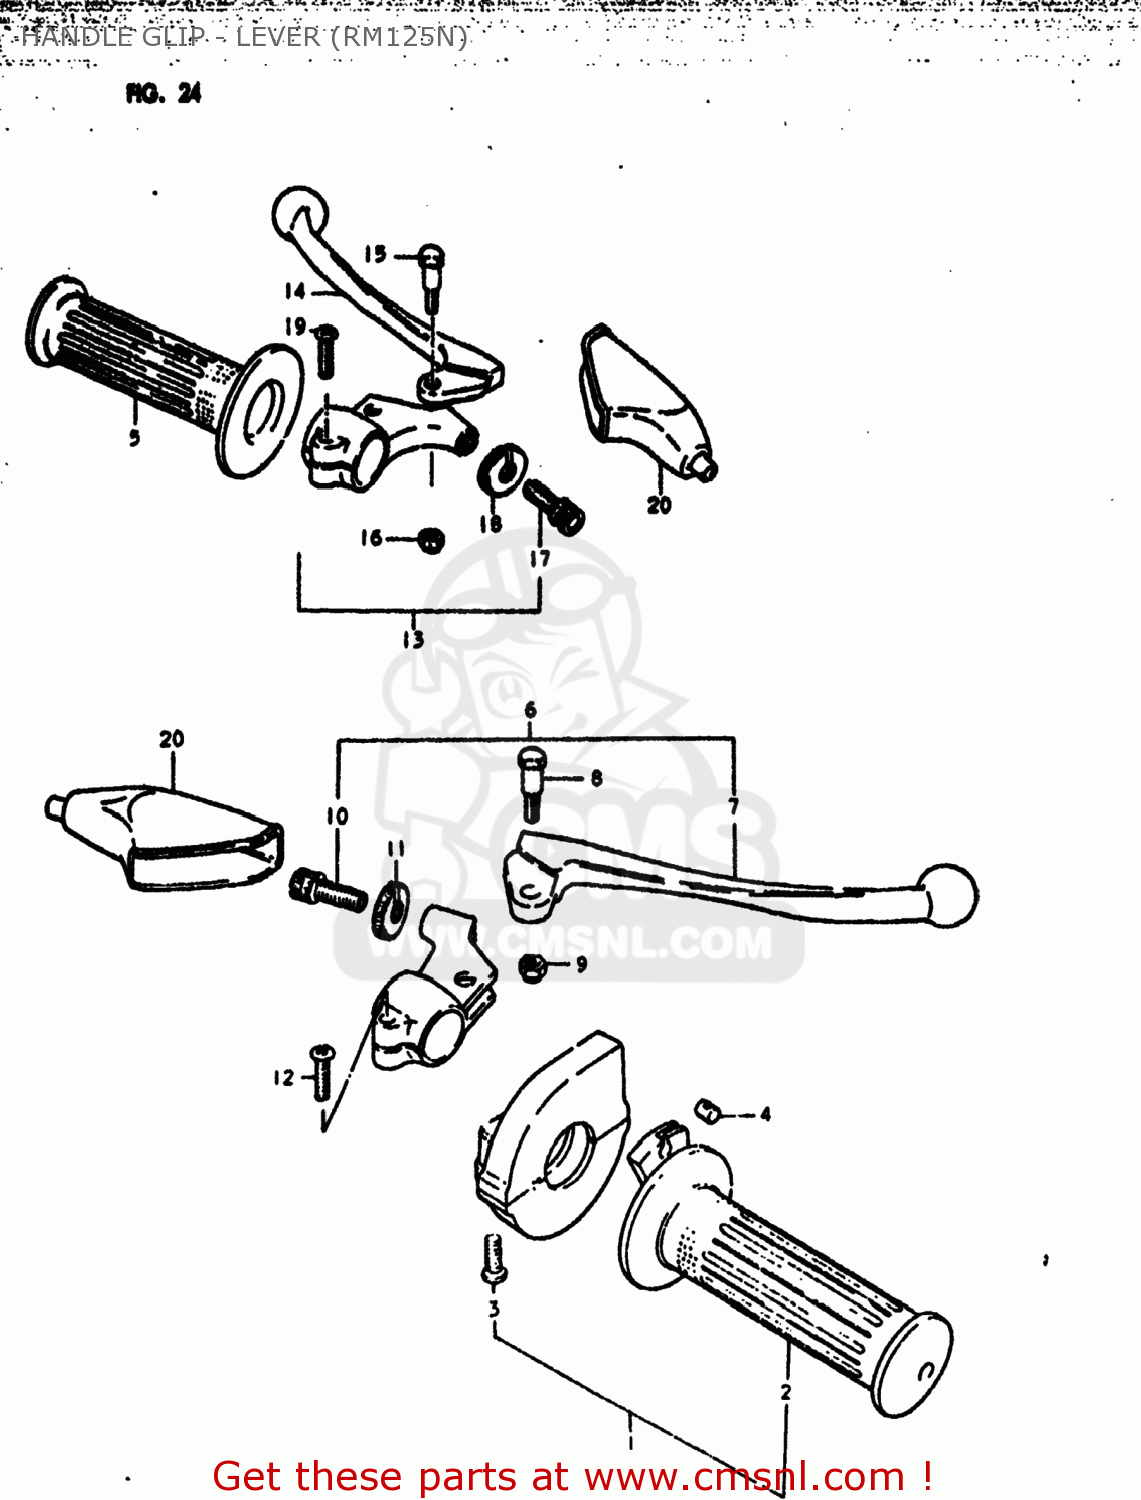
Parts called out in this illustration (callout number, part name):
1	GRIP ASSY,THROTTLE
2	GRIP,THROTTLE
3	SCREW
4	PIECE,THROTTLE END
5	GRIP,LEFT
6	LEVER ASSY,BRAKE
7	LEVER,BRAKE
8	BOLT,LEVER
9	NUT 6MM
10	ADJUSTER,CABLE
11	NUT,CABLE ADJUSTER
12	SCREW
13	LEVER ASSY,CLUTCH
14	LEVER,CLUTCH
15	BOLT,LEVER
16	NUT 6MM
17	ADJUSTER,CABLE
18	NUT,CABLE ADJUSTER
19	SCREW
20	COVER,CLUTCH LEVER
